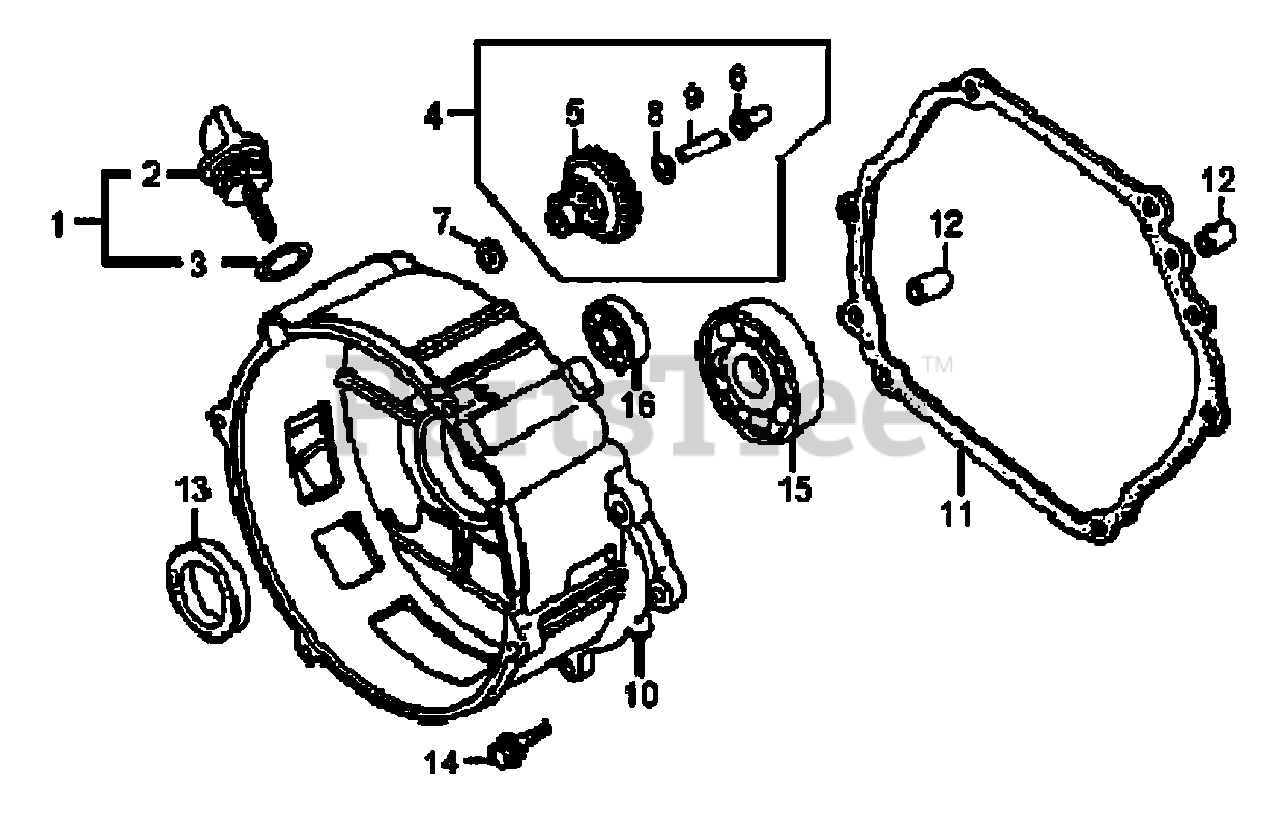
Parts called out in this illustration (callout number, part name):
1	CAP, COMPLETE, OIL FILLER(INC. #2 & #3)
2	CAP, OIL FILLER
3	O-RING, OIL FILLER CAP
4	GOVERNOR ASSY.
5	GOVERNOR GEAR
6	SLIDER, GOVERNOR
7	WASHER, PLAIN
8	CLIP, GOVERNOR SHAFT
9	SHAFT, GOVERNOR
10	CRANKCASE, COVER
11	GASKET, CRANKCASE COVER
12	PIN, DOWEL 8 x 12
13	SEAL, OIL 35 x 52 x 7
14	BOLT, FLANGE M8 x 40
15	BEARING, RADIAL BALL 6207
16	BEARING, RADIAL BALL 6202
